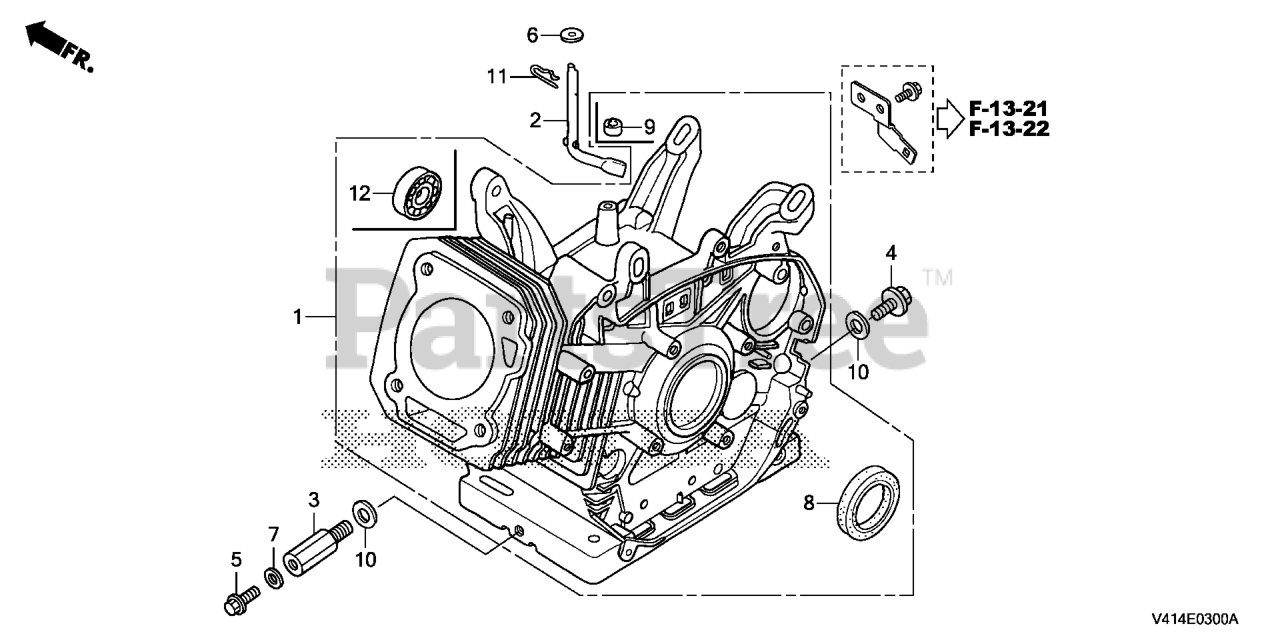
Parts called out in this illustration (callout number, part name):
1	CYLINDER ASSY.
2	SHAFT, GOVERNOR ARM
3	EXTENSION, OIL DRAIN
4	BOLT, DRAIN PLUG
5	BOLT, DRAIN PLUG
6	WASHER (8.2X17X0.8)
7	WASHER, DRAIN PLUG (10.2MM)
8	OIL SEAL (35X52X8) (NOK)
8	OIL SEAL (35X52X8)
9	OIL SEAL (8X14X5)
10	WASHER, DRAIN PLUG (12MM)
11	PIN, LOCK (10MM)
12	BEARING, RADIAL BALL (6202)
12	BEARING, RADIAL BALL (6202) (FUJIKOSHI)
